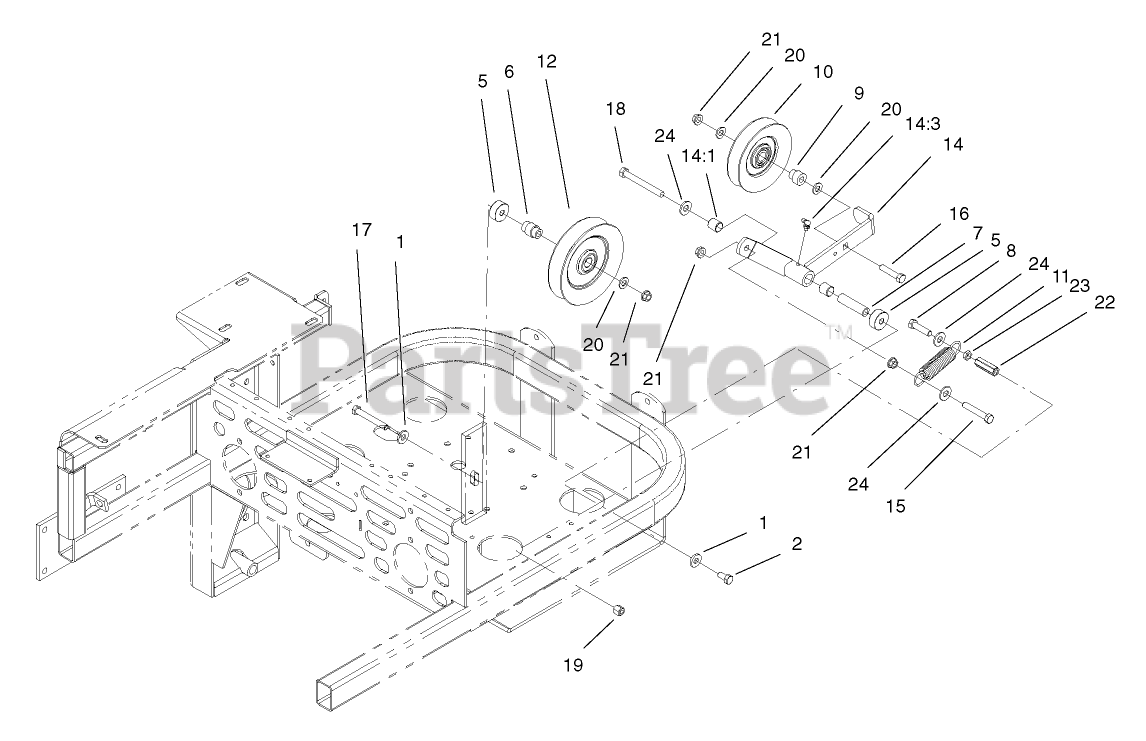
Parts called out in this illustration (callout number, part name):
1	WASHER-BELLEVILLE
2	SCREW-HH
5	Spacer-Idler
6	Bushing-Idler
7	BUSHING-PIVOT, IDLER
8	SCREW-HH
9	BUSHING-IDLER
10	Idler
11	SPRING-EXTENSION
12	PULLEY-IDLER
14	IDLER ARM ASM
14:1	SLEEVE-BEARING
14:3	FITTING-GREASE, 90 DEG
15	SCREW-HH
16	SCREW-HH
17	SCREW-HH
18	SCREW-HH
19	NUT-LOCK, NI
20	WASHER-FLAT
21	NUT-HHF, WHIZ
22	Nut-Coupling
23	NUT-JAM
24	WASHER-FLAT
